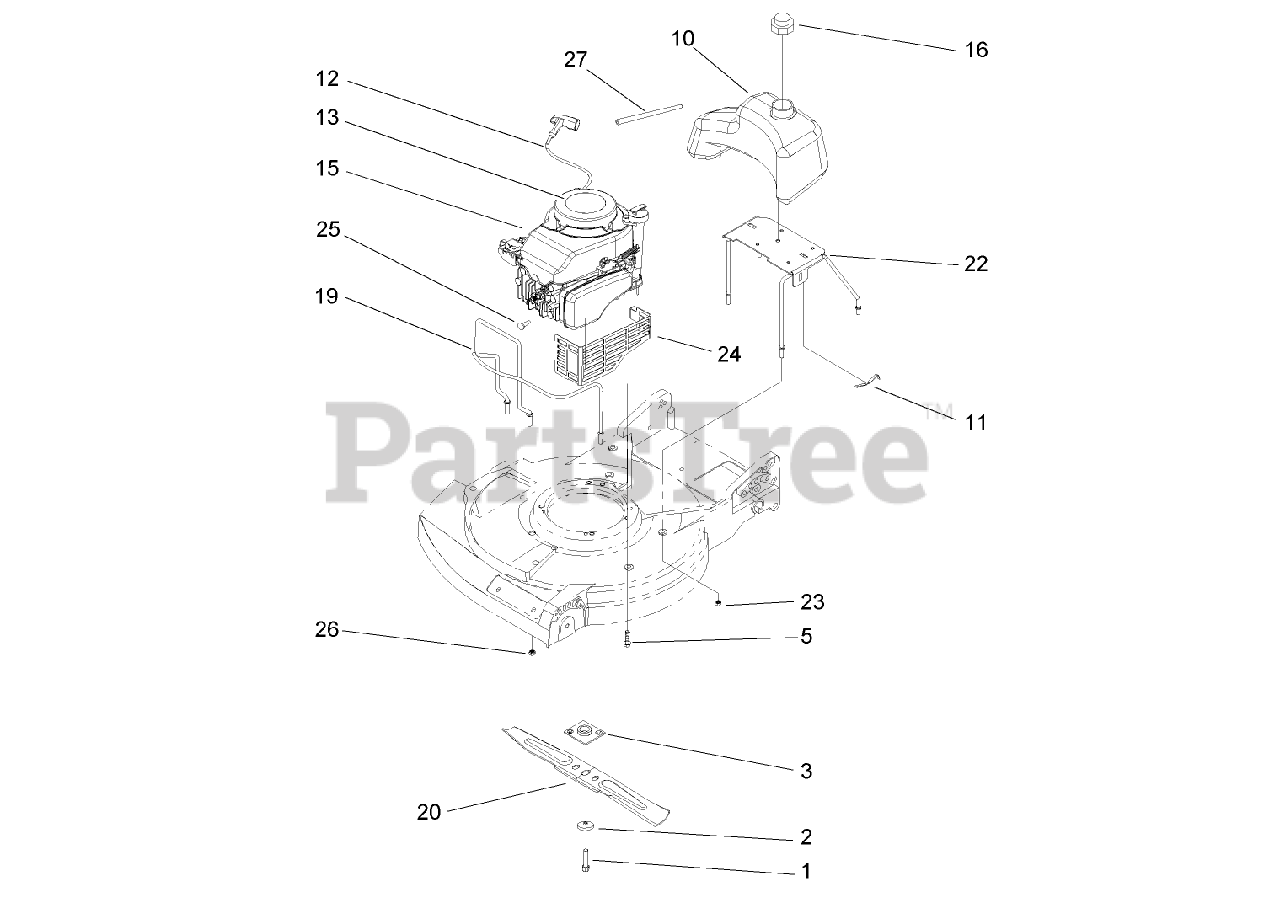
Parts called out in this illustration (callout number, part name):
1	BOLT-BLADE
2	SPACER-BLADE
3	PLATE AND COLLAR ASM
5	SCREW-MOUNT, ENGINE
10	TANK-FUEL
11	SPRING
12	STOP-ROPE
13	DECAL-RECOIL
16	GAS CAP ASM
19	GUARD-MUFFLER
20	Blade
20	BLADE-20.88 INCH
22	TANK BRACKET ASM
23	NUT-LOCK, NI
24	SHIELD-MUFFLER
25	SCREW-TAPTITE
26	NUT-LOCK, NI
27	GAS-LINE
